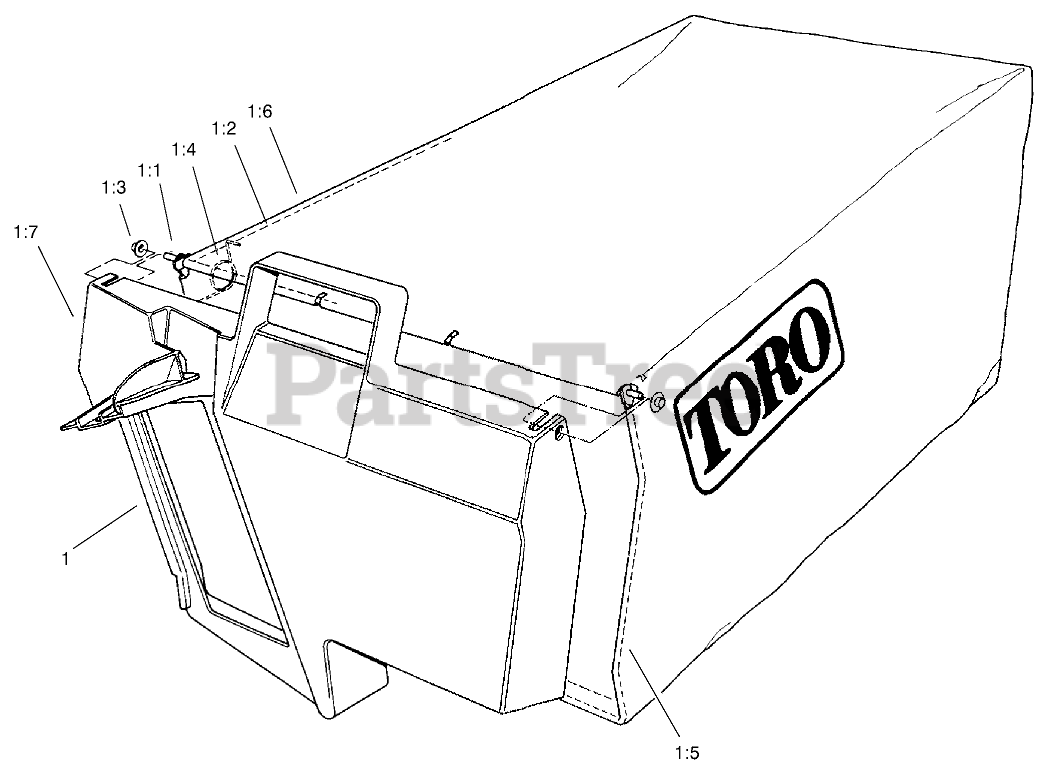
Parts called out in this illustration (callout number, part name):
1	Grass Bag ASM
1:1	HINGE-DOOR, BAG
1:2	FRAME-BAG, UPPER
1:3	NUT-PUSH
1:4	SPRING
1:5	FRAME-BAG
1:6	BAG-GRASS
1:7	DOOR-BAG, GRASS
